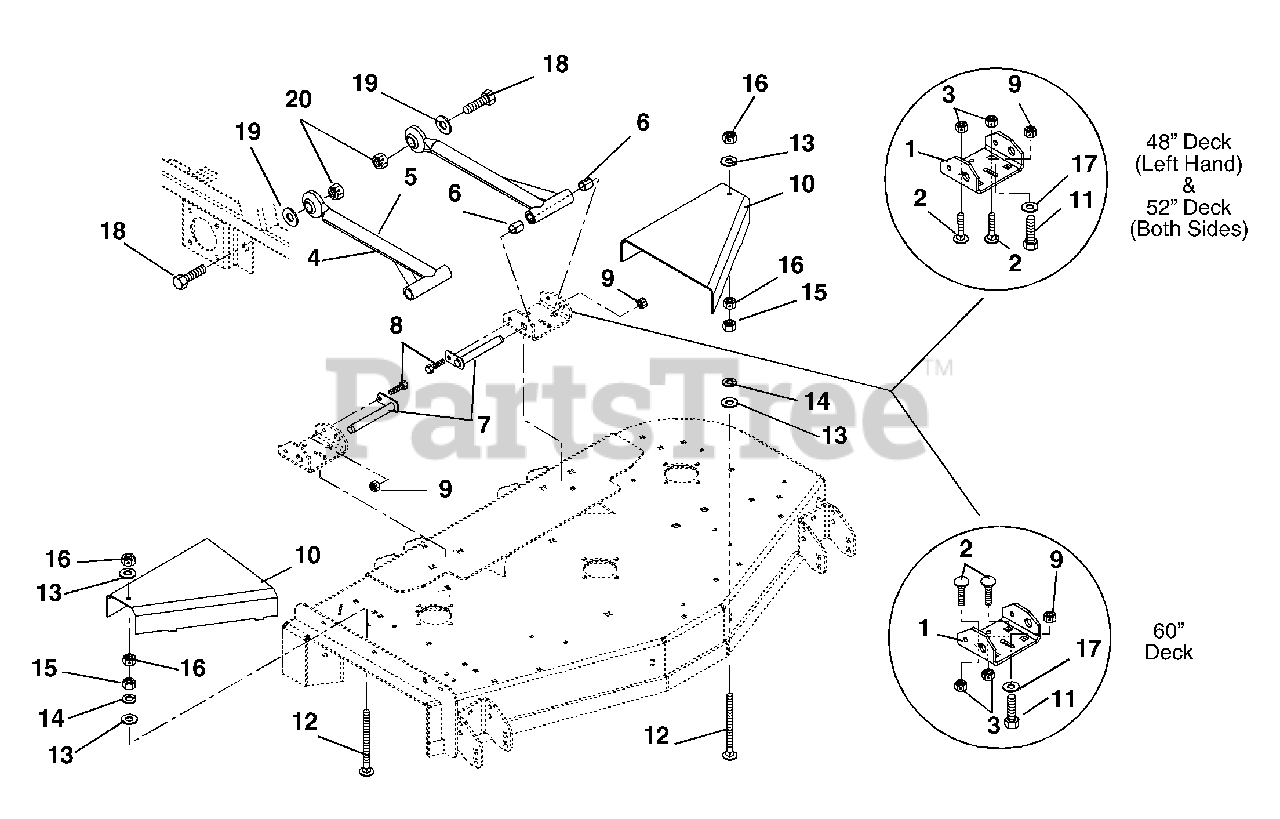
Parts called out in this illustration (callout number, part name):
1	BRKT, MOWER MOUNT - ORANGE
2	@BLT-RDHDSQNK .50-13X.75 G5YZ
3	NUT-LK-CTR-JAM .50-13 YWZC(ND)
4	ASSY, MOWER MOUNTING
5	MOWER MTG ARM - BLACK
6	BRG, .750 X .875 X 1.000
7	WELDMENT, MOWER MTG. PIN
8	@BLT-HEX .38-16X.75 GR5 YWZC
9	@NUT-LK-TOP-FLG .38-16 YWZC
10	GUARD, PULLEY LH - ORANGE
10	GUARD, PULLEY RH - ORANGE
11	@BLT-RDHDSQNK .38-16X.75 G5YZ
12	BLT-RDHDSQNKFTH.312-18X3.50YWZ
13	@WSHR-FL-STL.344X.688X.065YWZC
14	@WSHR-LK .31X.078 REG YWZC
15	@NUT-HEX .31-18 YWZC
16	@NUT-LK-CTR .31-18 YWZC
17	@WSHR-FL-STL.406X.812X.065 YWZ
18	BLT-HEX .875-9X2.75 GR5 YWZC
19	WSHR-FL-STL .890X1.500X.1196YZ
20	NUT-LK-CTR .875-9 YWZC
